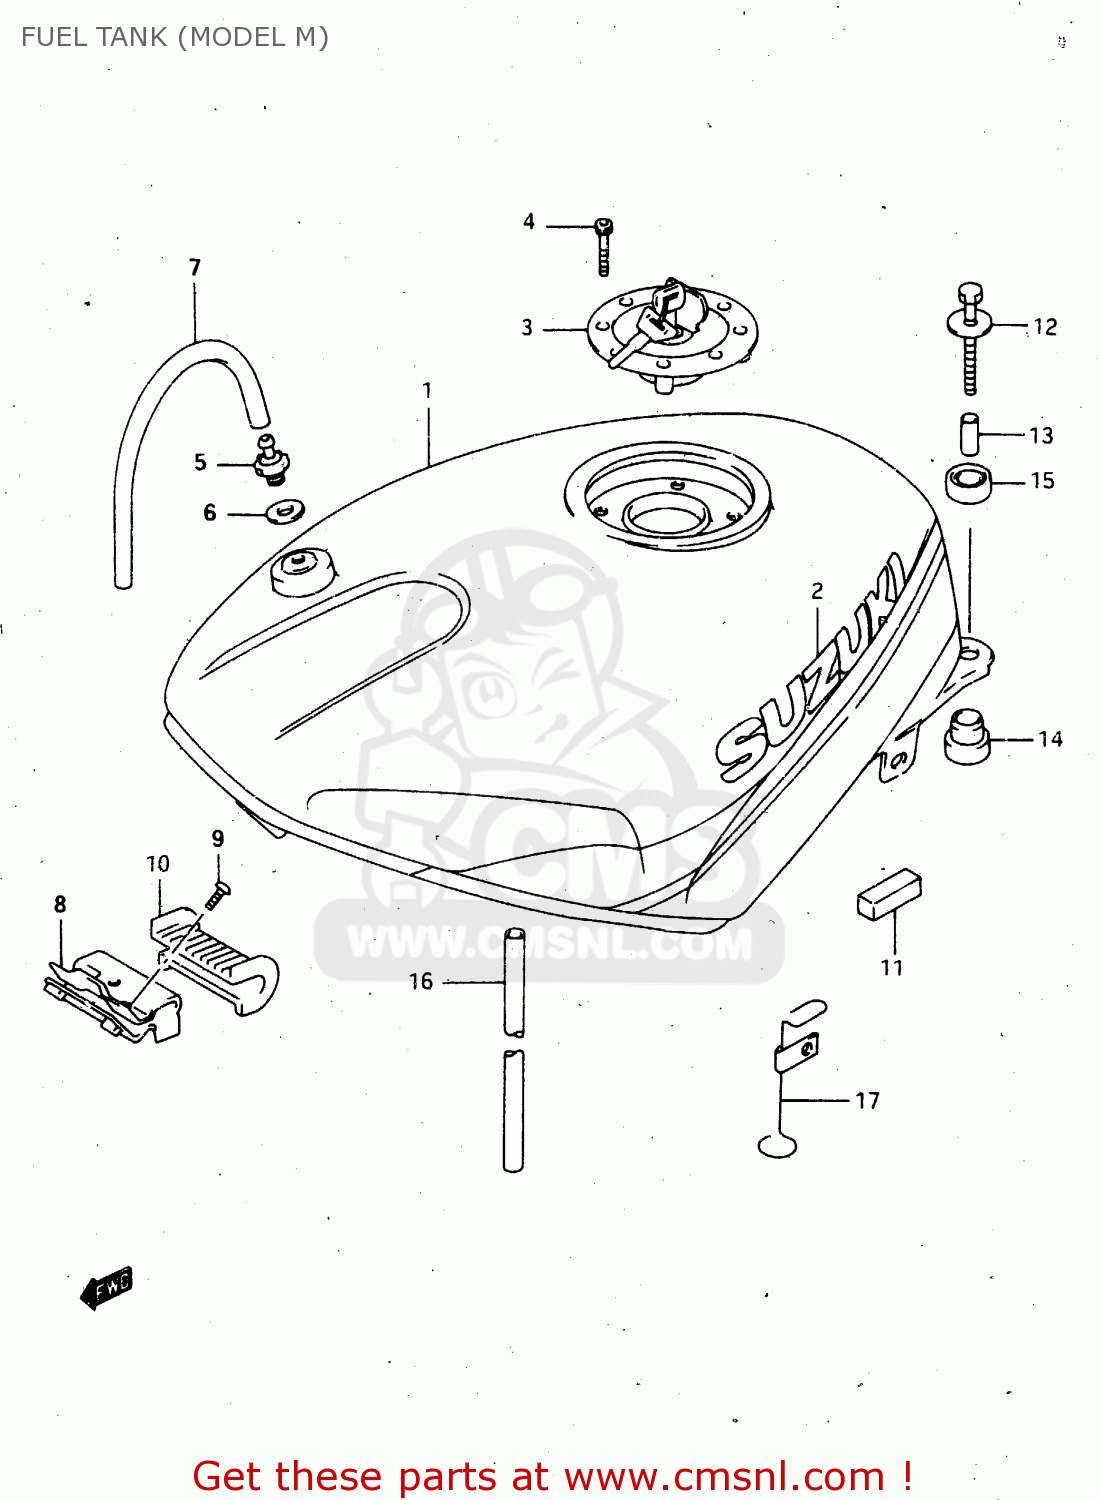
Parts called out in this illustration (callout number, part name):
1	TANK ASSY, FUEL
2	EMBLEM (SILVER)
3	CAP SET,FUEL TANK
4	BOLT(5X20)
5	PLUG,FUEL TANK BREATHER
6	GASKET(12.5X20X2.5) (NAS)
7	HOSE(5X8.2X600)
8	BRACKET,FUEL TANK
9	SCREW
10	CUSHION,FUEL TANK,FRONT
11	CUSHION,FUEL TANK SIDE
12	BOLT
13	SPACER
14	CUSHION
15	CUSHION
16	HOSE(5X8.2X2000)
17	GUIDE, DRAIN HOSE
